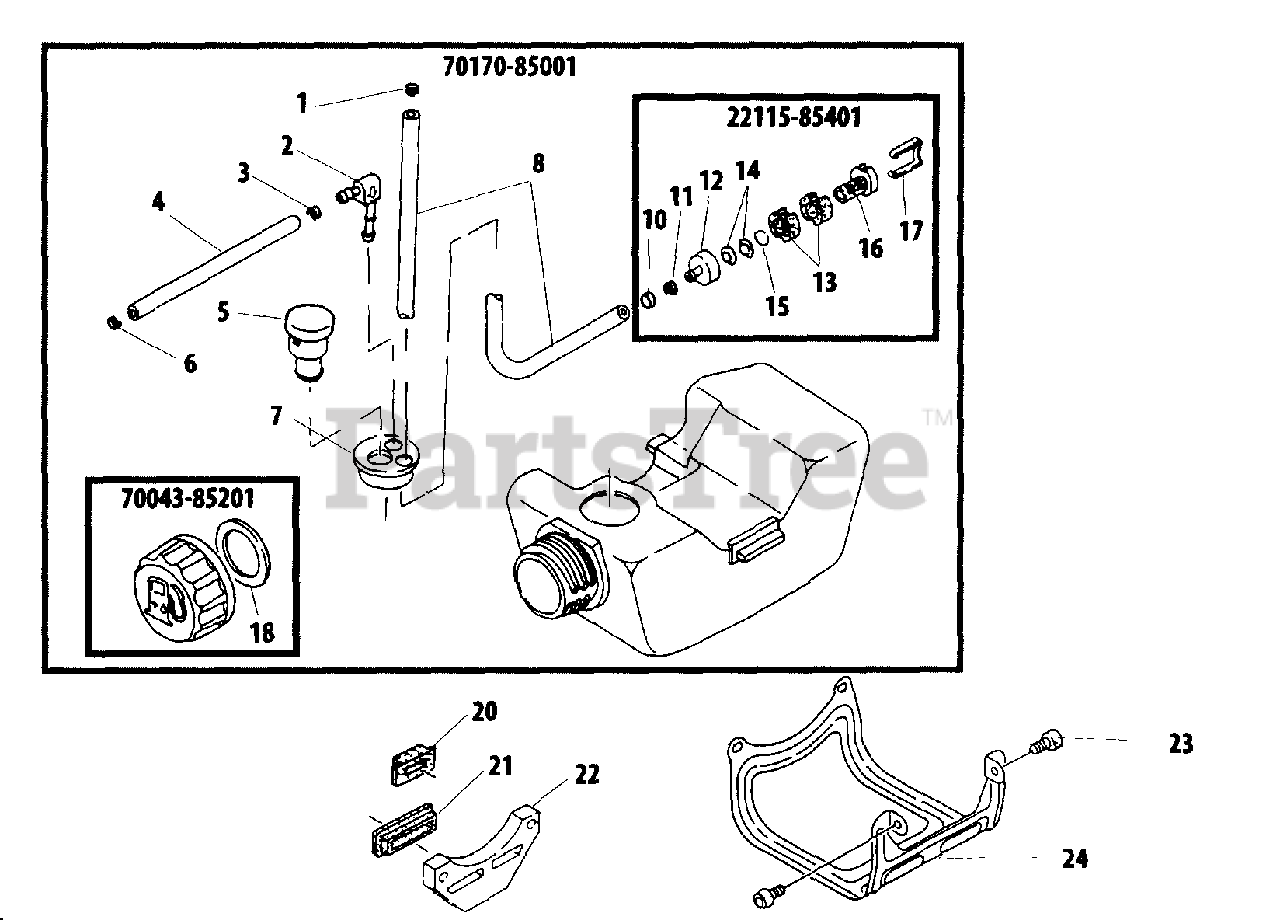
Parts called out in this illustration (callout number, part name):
1	CLIP
2	CONNECTOR, PIPE
3	CLIP
4	PIPE, RETURN
5	VENT ASSY
6	CLIP
7	GROMMET, FUEL TANK
8	PIPE, FUEL
10	VALVE, CHECK
11	CLIP
12	WEIGHT, FUEL LINE
13	FILTER, FUEL
14	STRAINER
15	RING, RETAINING
16	BODY, FUEL FILTER
17	CLIP, FILTER
18	GASKET, FUEL CAP
20	CUSHION, FUEL TANK
21	CUSHION, FUEL TANK - REAR
22	BRACKET, FUEL TANK
23	BOLT M5×12
24	GUARD, METAL FUEL TANK
22115-85401	FILTER, FUEL
70043-85201	CAP ASSY, FUEL
70170-85001	FUEL TANK ASSY
